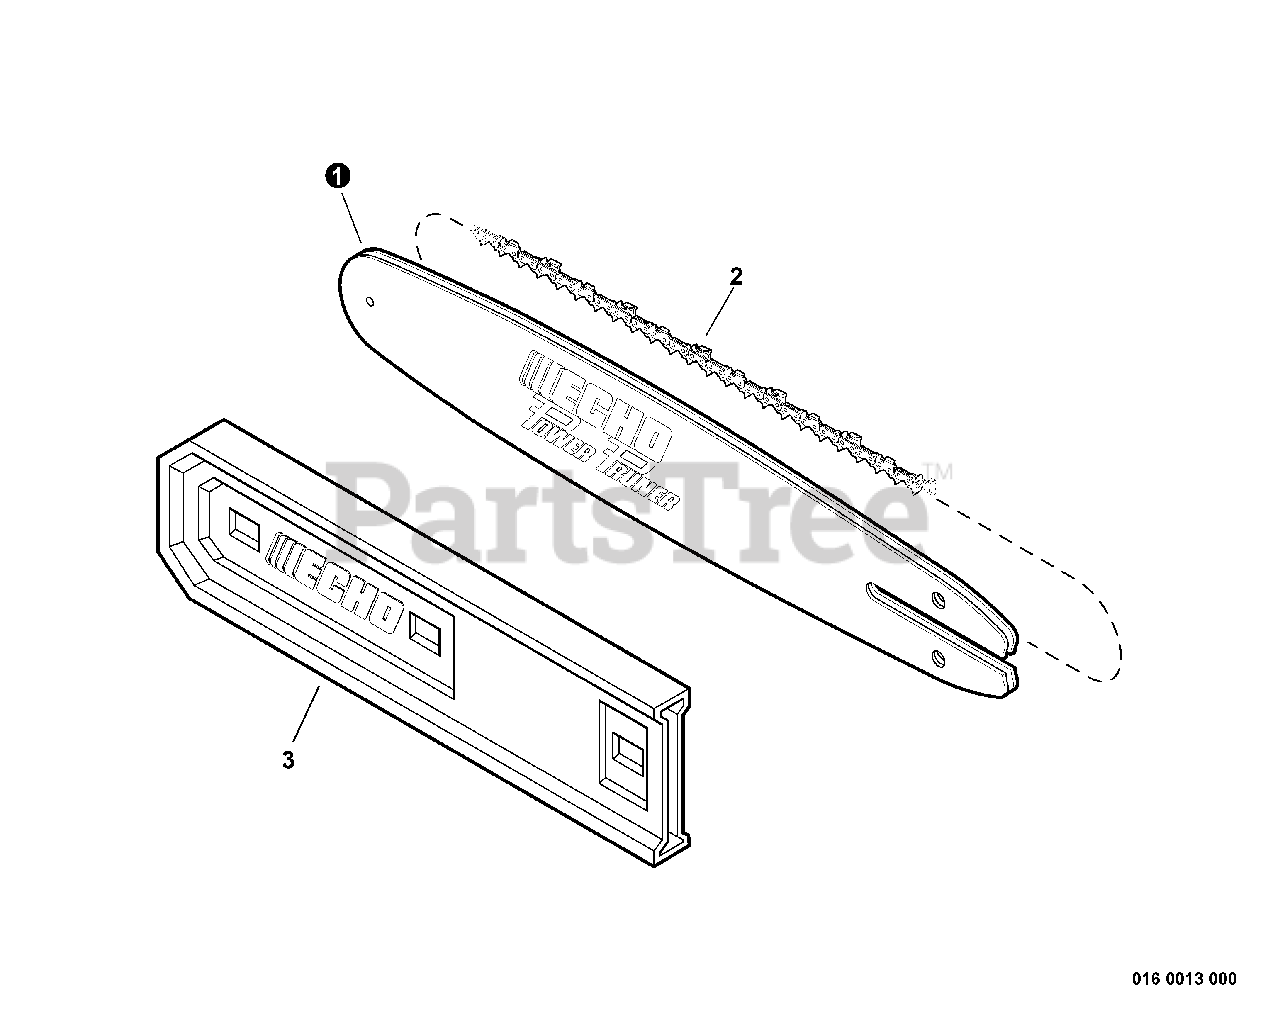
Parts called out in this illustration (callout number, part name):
1	GUIDE BAR - 10" (25cm)
2	SAW CHAIN - 10" (25cm)
3	COVER, GUIDE BAR - 10" (25cm)
